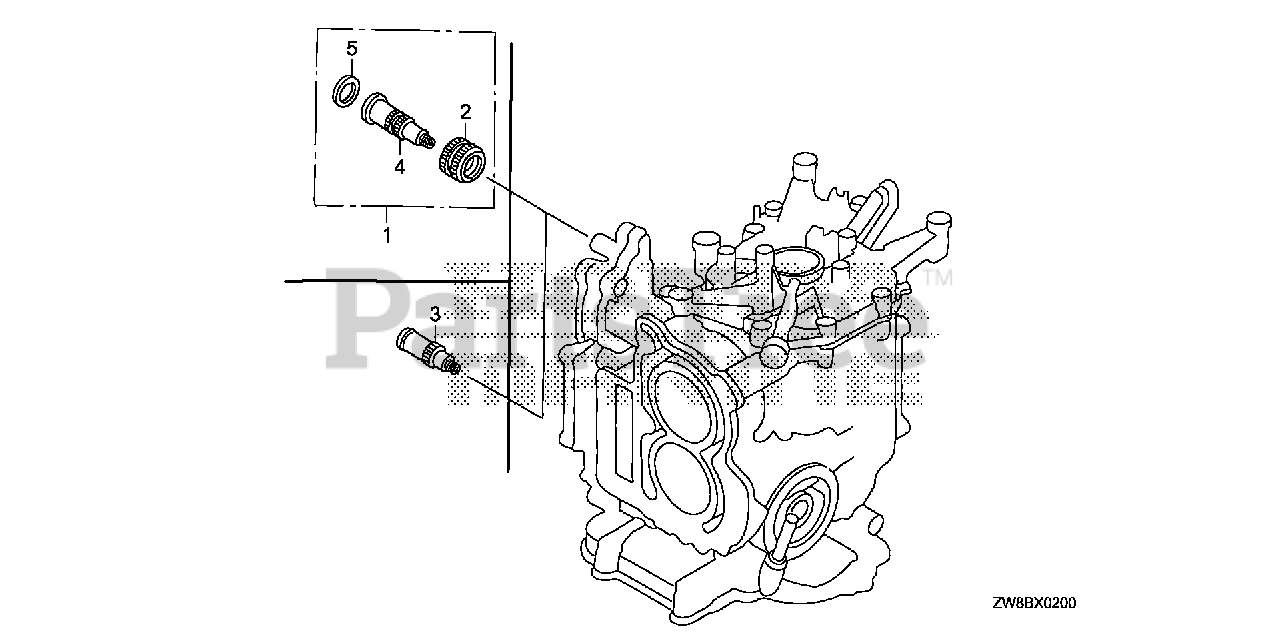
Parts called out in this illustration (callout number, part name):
1	JOINT KIT, WATER HOSE
2	NUT, WATER MOUTH Use from Frame SN 1000929.
3	JOINT, WATER HOSE
4	JOINT, WATER HOSE
5	SEAT, WATER MOUTH Use from Frame SN 1000929.
